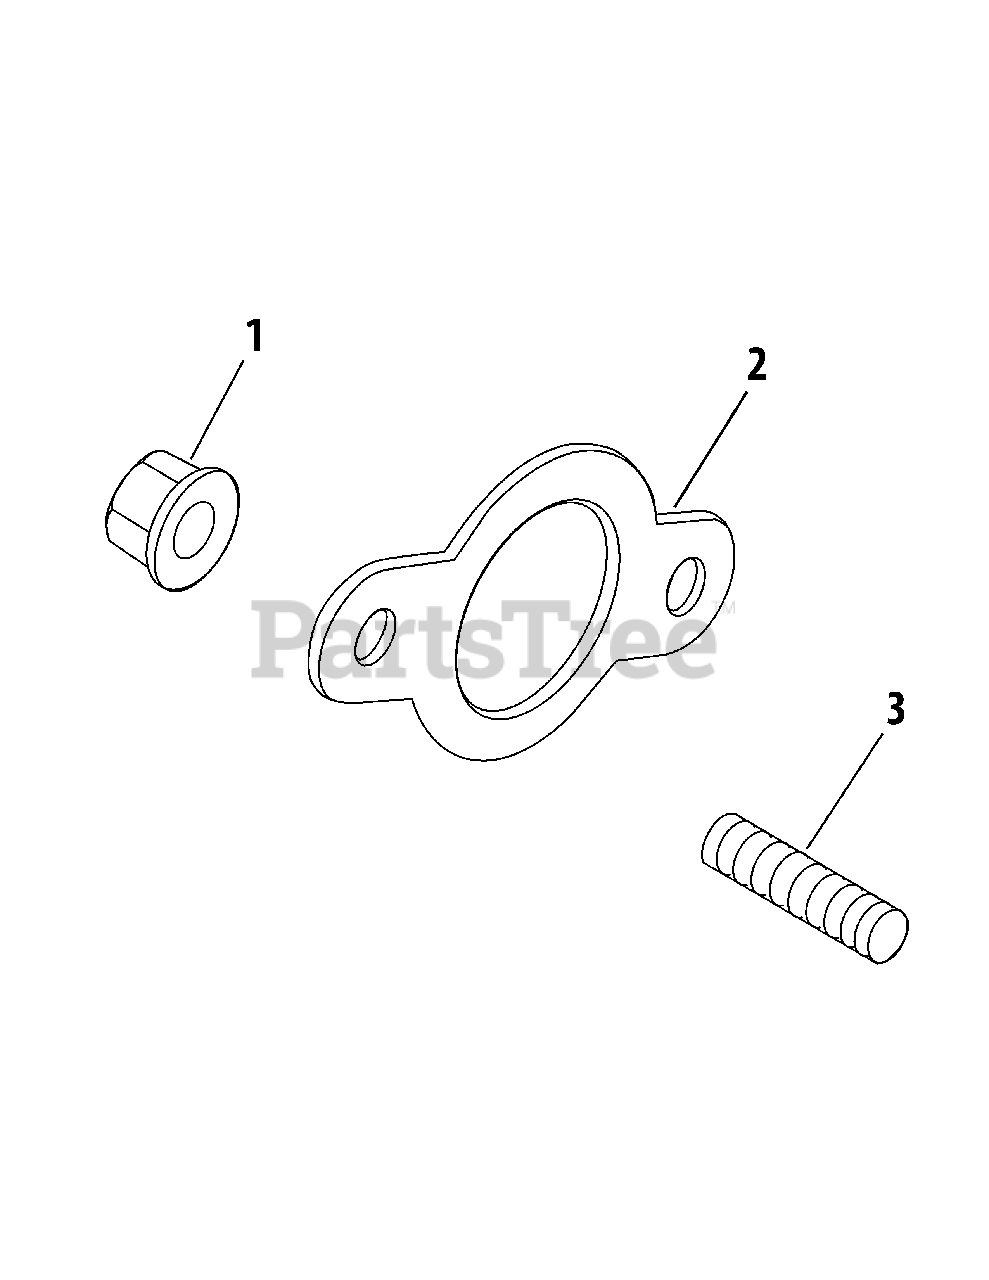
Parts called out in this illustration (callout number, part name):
1	Nut, Muffler Mounting, M8 x 1.25
2	Gasket, Exhaust
3	Stud, Exhaust, M8 x 1.25 x 33
